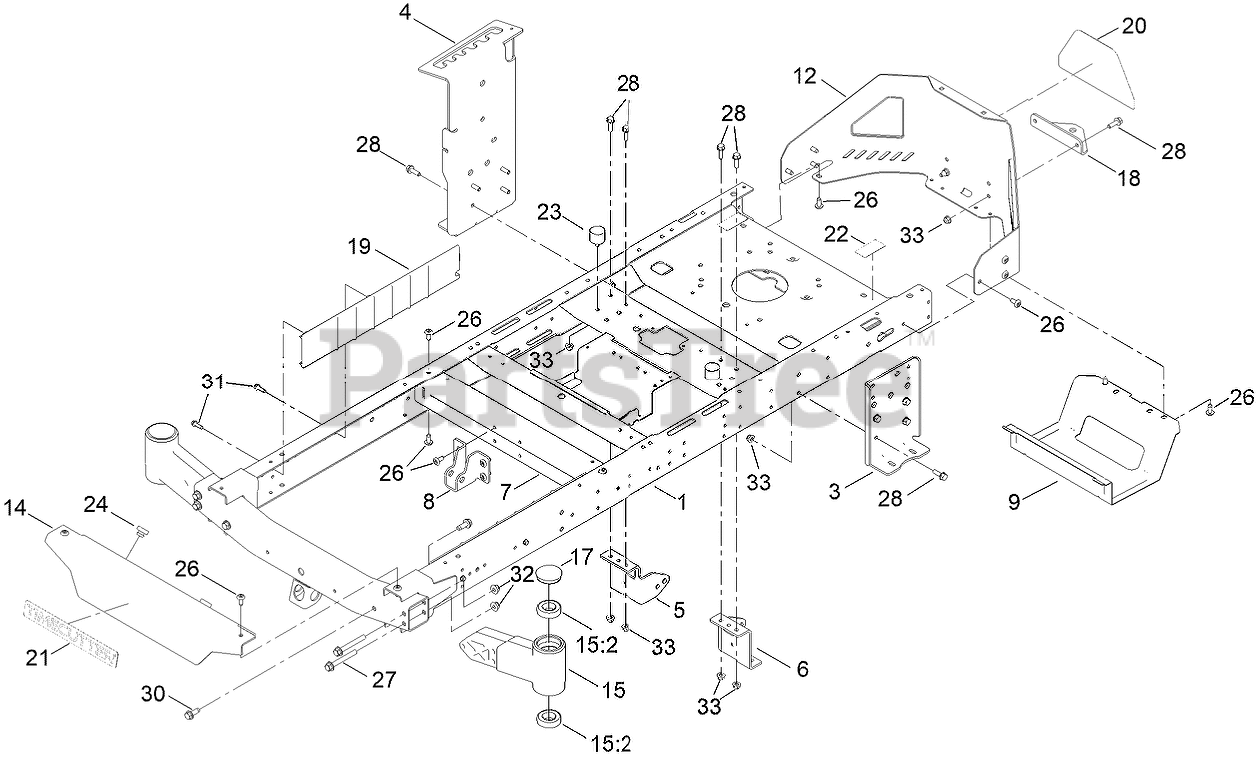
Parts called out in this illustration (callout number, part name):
1	FRAME ASM - RIVETED/WELDED
3	PLATE-MOUNT, HYDRO
4	PLATE-MOUNT HYDRO, RH
5	MOUNT-HYDRO, FRONT (RIGHT)
6	MOUNT-HYDRO, FRONT (LEFT)
7	BRACE-CROSS, LOWER (PAINTED)
8	BRACKET-MOUNT DAMPER, LOWER
9	GUARD-MUFFLER
12	GUARD-ENGINE
14	FOOTREST (PAINTED)
15	AXLE STUB ASM
15:2	BEARING-BALL
17	CAP-GREASE
18	BRACKET-HITCH
19	GUARD-RAIL
20	DECAL-TIMECUTTER
21	DECAL-TIMECUTTER
22	DECAL-BYPASS
23	BUMPER-RUBBER
24	BUMPER-RUBBER
27	SCREW-HHF
28	SCREW-HHF
30	SCREW-HWH
31	SCREW-HWH
32	NUT-HF, NI
33	NUT-HF, NI
